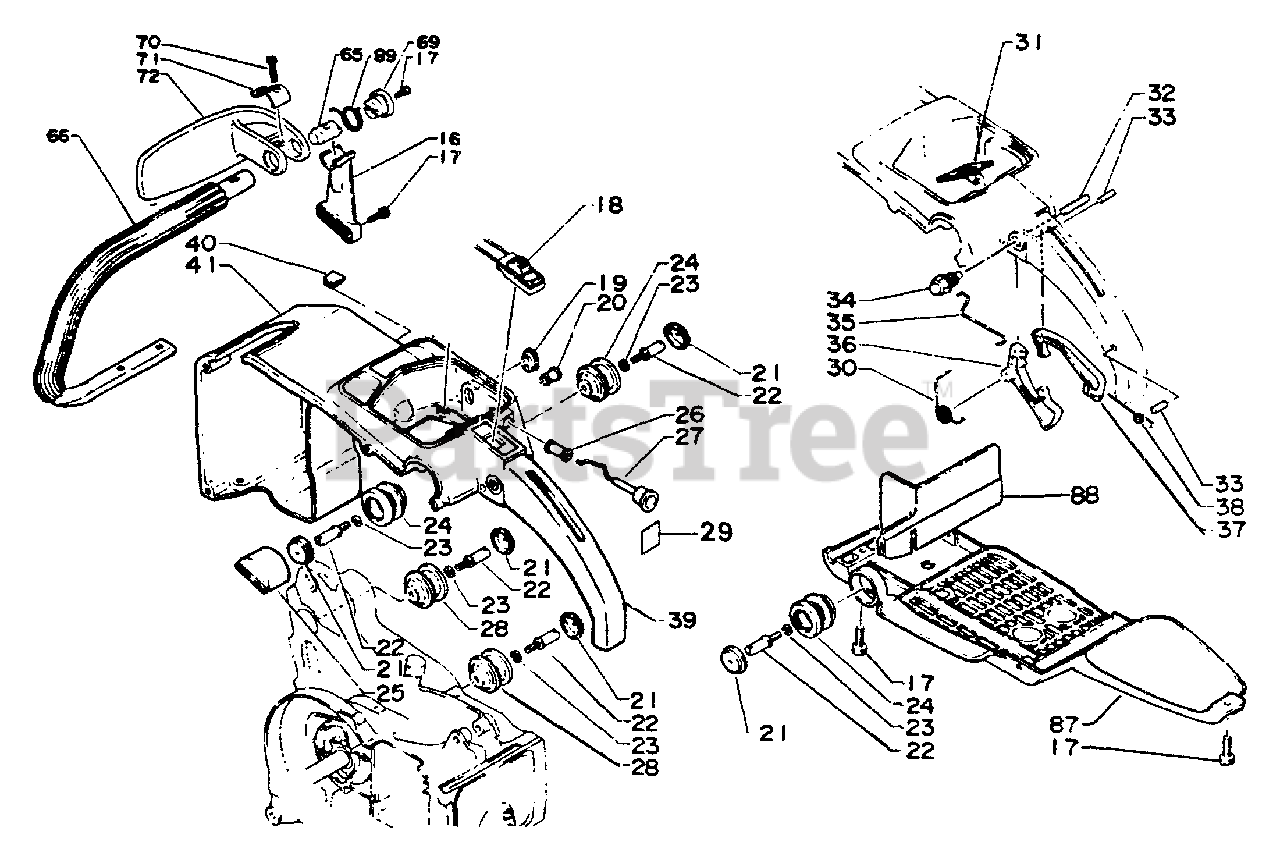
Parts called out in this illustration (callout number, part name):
16	SUPPORTER
17	BOLT 5×20
18	SWITCH, STOP
20	GROMMET
21	CAP, CUSHION
23	WASHER, SPRING 5
25	COVER, CUSHION
26	GROMMET
27	ROD, CHOKE
29	LABEL - CHOKE
30	SPRING, THROTTLE RETURN
32	PIN, SPRING 5×25
33	PIN, SPRING 4×13
34	LATCH, THROTTLE
35	ROD, THROTTLE
36	CONTROL, THROTTLE
37	LOCKOUT, THROTTLE
38	SPRING, LOCKOUT RETURN
39	GRIP, HANDLE
41	HANDLE, REAR
66	HANDLE, FRONT
69	RETAINER
70	BOLT 5×30
71	STOPPER
72	GUARD
73	COVER
87	SUPPORTER, BOTTOM
88	INSULATOR
